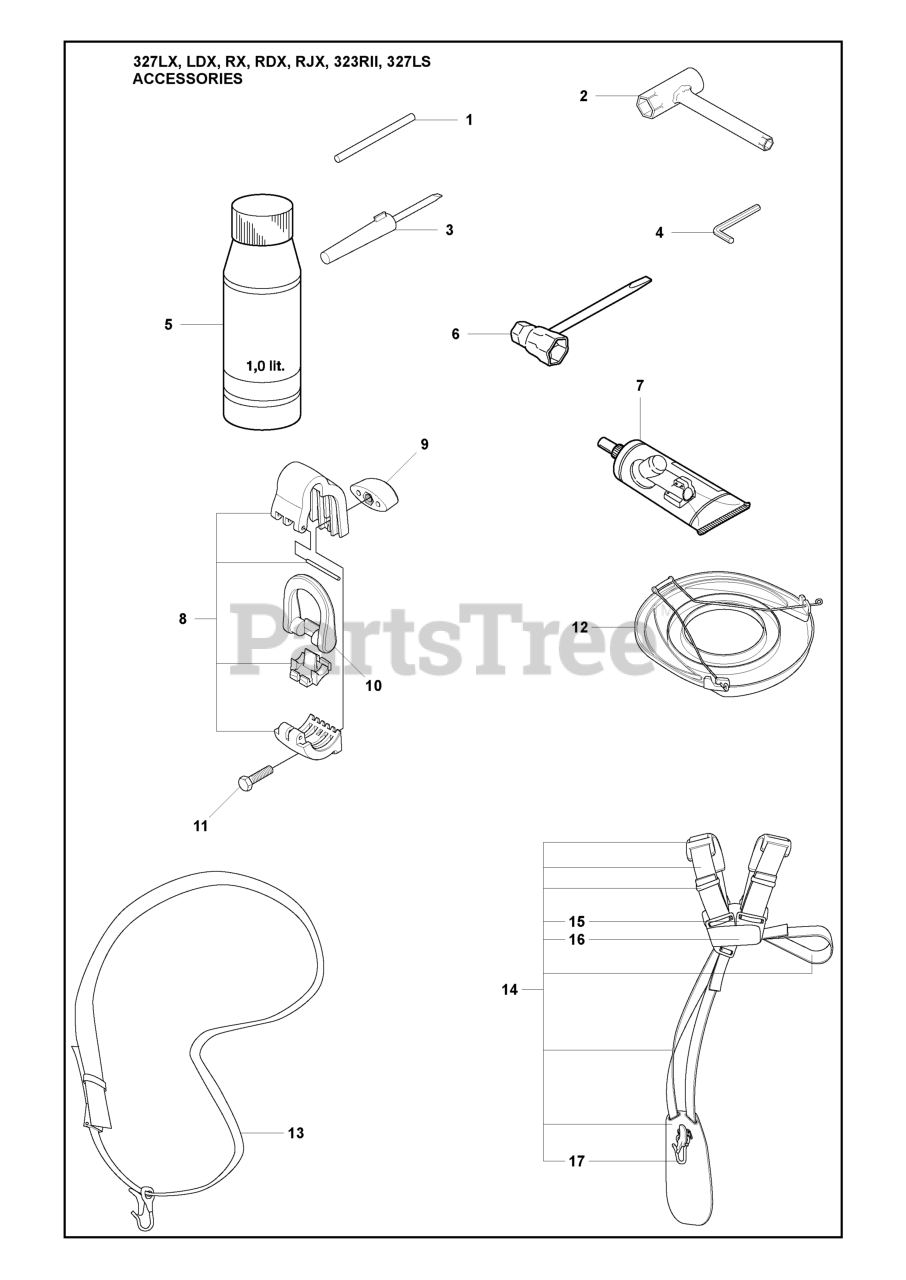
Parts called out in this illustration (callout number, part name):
1	LOCKING PIN
2	COMBI WRENCH
3	SCREWDRIVER
4	L-KEY WRENCH
5	Air Filter Oil, HVA 1L Bottle
6	COMBI TOOL
7	BEVEL GEAR GREASE
8	HANGING BRACKET
11	SCREW M6S 5X20
12	BLADE GUARD TRANSPORT
13	STRAP
13	Shoulder Strap with Sign
14	HARNESS DUO
14	Hip Pad Harness
17	HOOK, CPL.
